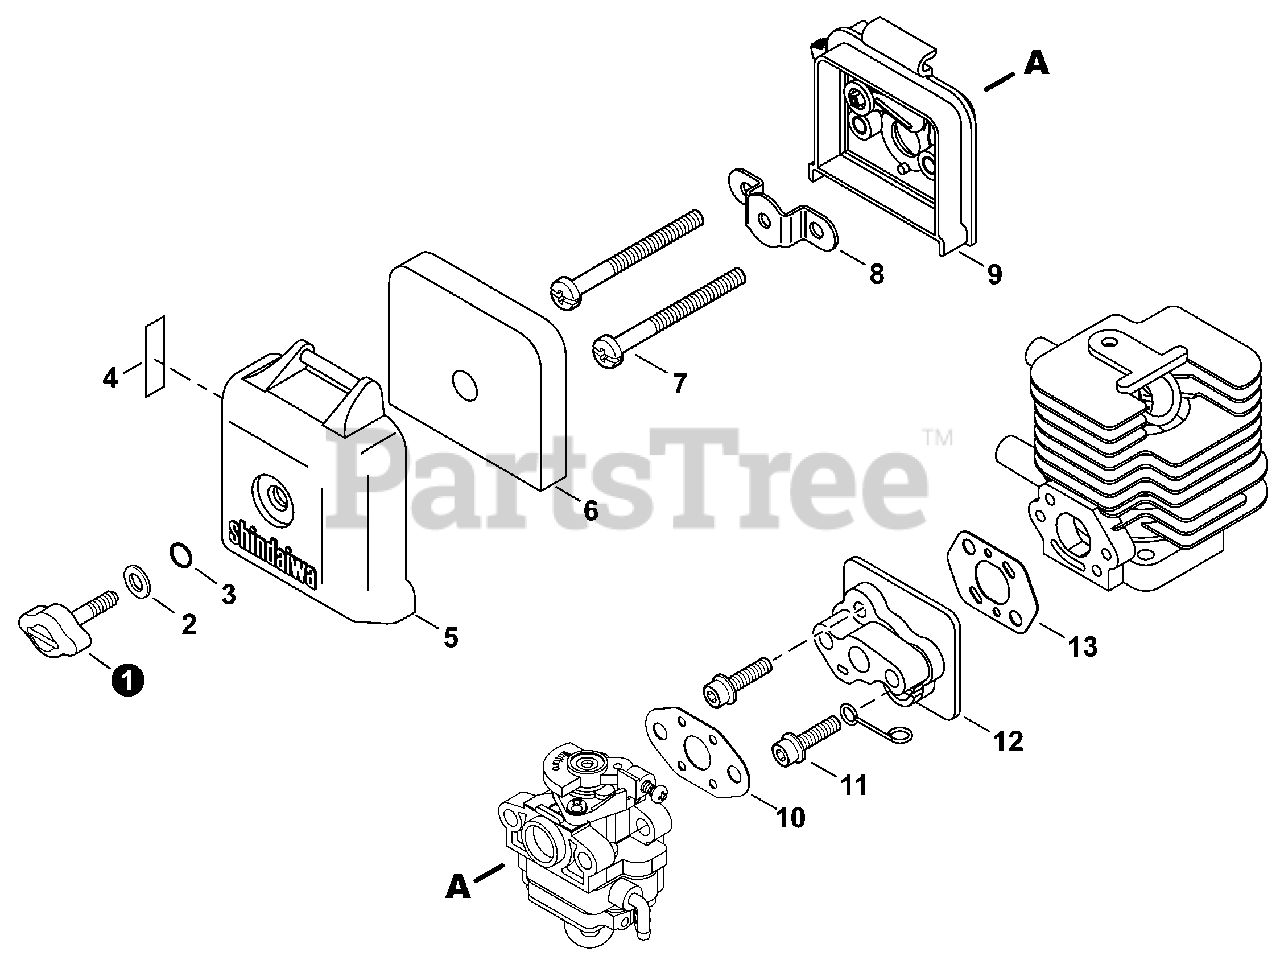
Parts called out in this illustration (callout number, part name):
1	THUMBSCREW
2	WASHER, CONE M6
4	LABEL - CHOKE
5	COVER, AIR FILTER
6	FILTER, AIR
7	SCREW M5x60
8	BRACKET
9	CASE, AIR FILTER
10	GASKET, CARBURETOR
11	BOLT M5x30
12	INSULATOR, INTAKE
13	GASKET, INTAKE
